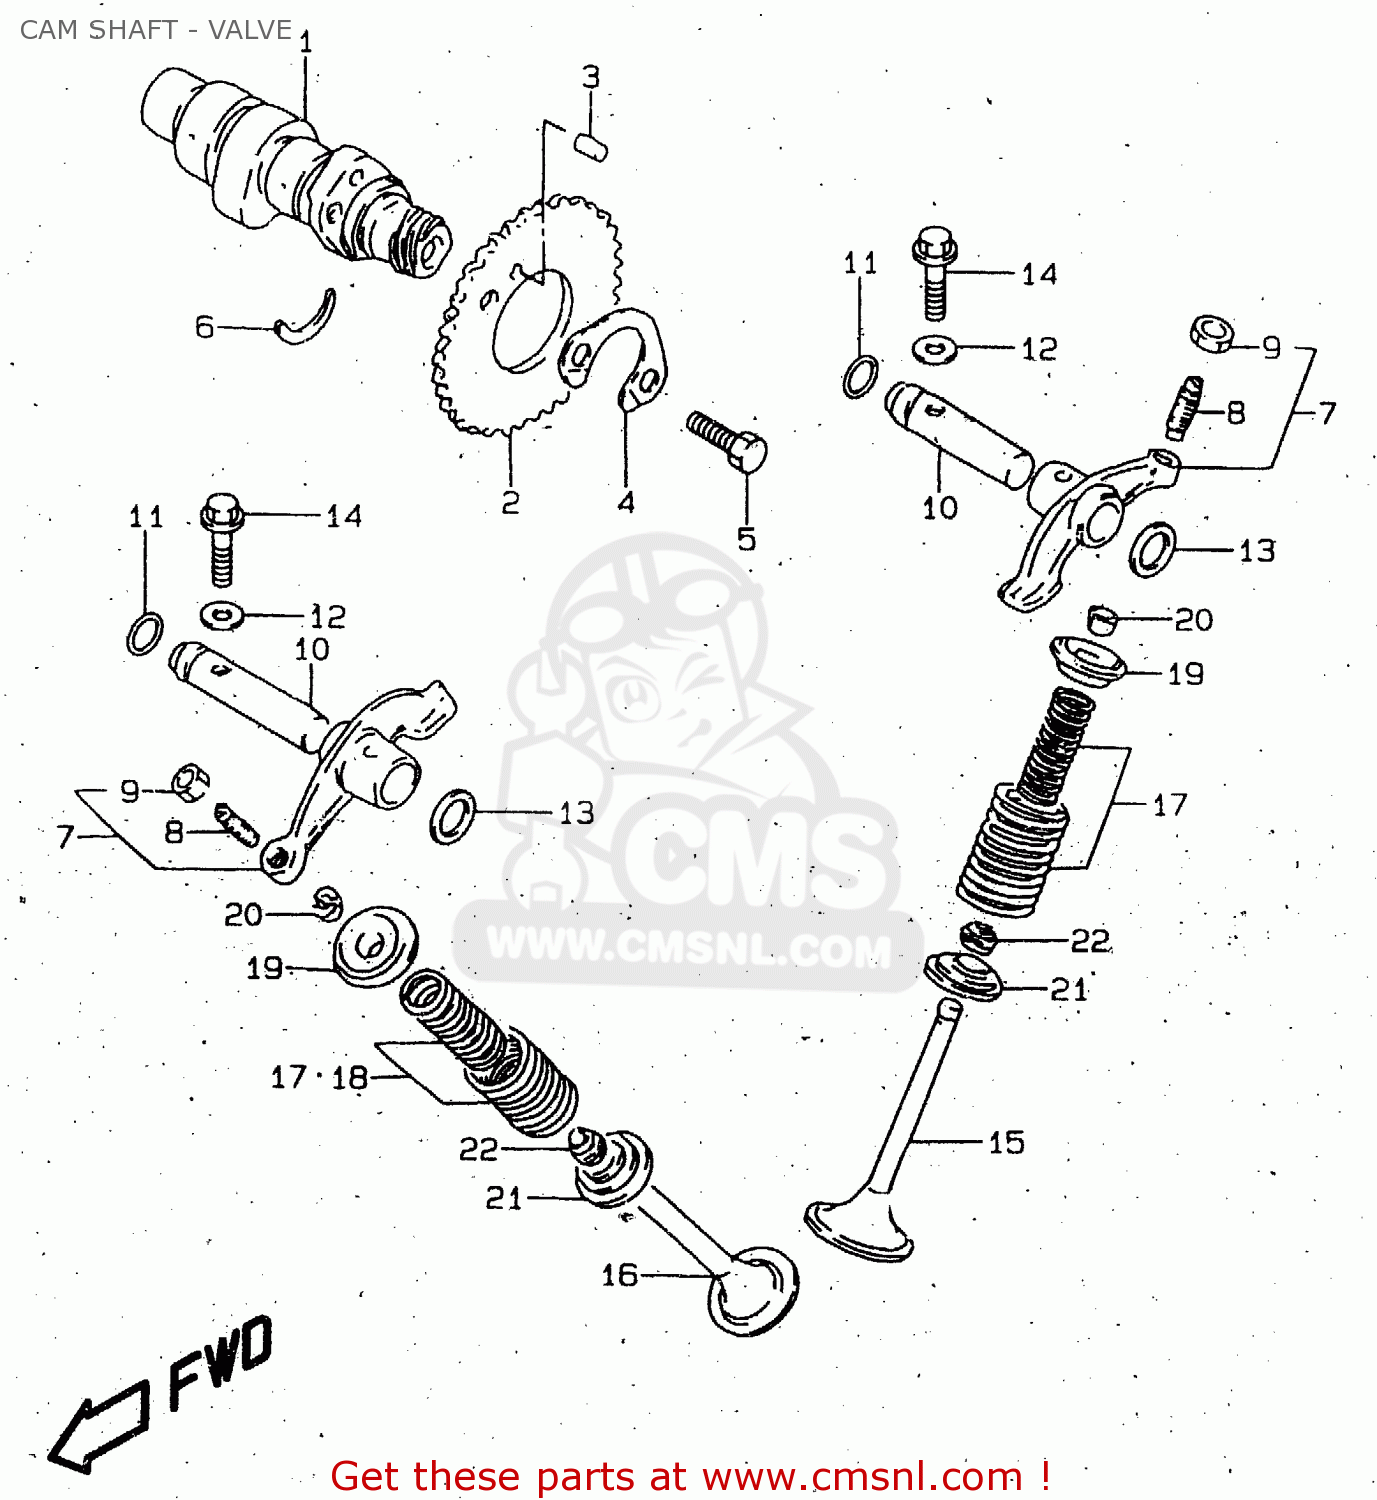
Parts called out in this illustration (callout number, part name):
1	CAMSHAFT
2	SPROCKET,CAMSHAFT
3	PIN(5X8)
4	WASHER,SPROCKET
5	BOLT(6X10.5)
6	C RING
7	ARM ASSY,VALVE ROCKER
8	SCREW,TAPPET ADJUSTING
9	NUT,ADJUSTING SCREW
10	SHAFT,VALVE ROCKET
11	O RING(D:1.9,ID:8.6)
12	GASKET(5.8X13X1.2) (NAS)
13	WASHER
14	BOLT
15	VALVE,INTAKE
16	VALVE,EXHAUST
17	SPRING SET,VALVE
18	SPRING SET,VALVE
19	RETAINER,VALVE SPRING
20	COTTER,VALVE
21	SEAT,VALVE SPRING
22	SEAL,OIL(5.5X11X8.2)
